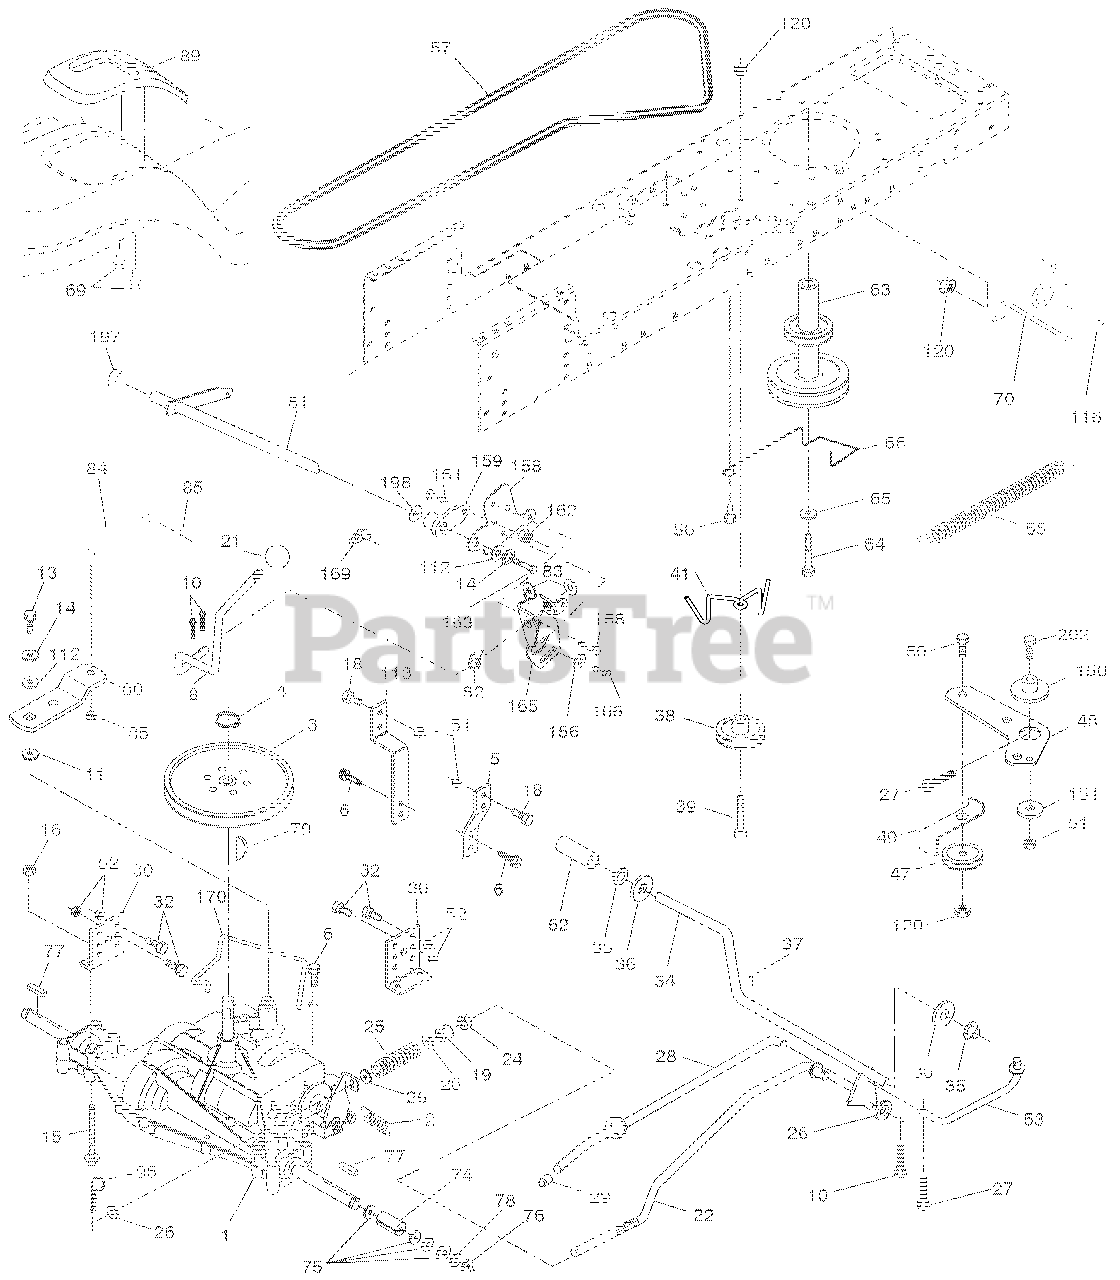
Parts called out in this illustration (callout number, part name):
2	Spring Return Brake T/a Zinc
3	PULLEY.TRANSAXLE.18/20"TIRES
4	Ring, Retainer
5	Strap Torque 30 Degrees
6	SCREW.5/16-18X3/4.SMGML.TAP/R
8	Rod Shift Fender Adjust Lt
10	Pin Cotter 1/8 x 1 Cad
11	WASHER.PLATE.SHF..388 SQ.HOLE
13	BOLT.1/4-28 UNF.GR8.W/PATCH
14	Washer, Lock 1/4
15	BOLT.HEX.FLGHD.5/16-18.GR.5
16	Locknut, Washer Insert 5/16-18
18	Bolt, Fin Hex 3/8-16 unc x 1
19	Locknut, Washer Insert 3/8-16
22	Rod Brake Blk Zinc 26 840
24	Nut, Hex, Jam 3/8-16
25	Spring Rod Brake 2 00 Zinc
26	WASHER.13/32 X 13/16 X 16 GA.
27	PIN.COTTER.1/8 X 3/4.CAD.
28	Rod Brake Parking LT/YT
29	Cap Brake Parking
30	Bracket Mtg Transaxle
32	Bolt, Hex Head 5/16-18 x 3/4
34	Shaft Asm Pedal Foot
35	BEARING.NYLON.BLK..629 ID.
36	Washer 21/32 x 1 x 16 Ga.
37	Pin Roll 3/16 x 1"
38	Pulley Composite Flat
39	BOLT.RDHD.3/8-16UNC X2-3/4 GR5
41	Keeper Belt Flat Idler
47	Pulley Idler V Groove
48	Bellcrank Asm
49	Retainer Belt Style Spring
50	BOLT.CARR.SH.3/8-16X1-1/2.GR5
51	Nut, Hex, Crownlock 3/8-16
52	Nut, Hex, Crownlock 5/16-18
53	Link Clutch
55	SPRING.RETURN.CLUTCH.6.75
56	Screw 3/8-16 x <
57	V-Belt Ground Drive
62	COVER.PEDAL.BLK.ROUND
63	Engine Pulley
64	BOLT.HEX.7/16-20X4XGR5-1.5THR.
65	WASHER.LOCK.HVY HLCL.SPR.7/16
66	Keeper Belt Engine Foolproof
69	SCREW.HEX.WSH.HI-LO.1/4X1/2UNC
70	Guide Belt Mower Drive RH
74	SPACER.AXLE.HYDRO/PEERLES
75	WASHER.25/32 X 1 1/4 X 16 GA.
76	E-RING.#5133-75
77	KEY.SQUARE.2.0 X .1845/.1865
78	WASHER.25/32 X 1-5/8 X 16GA.
79	Key Woodruff #9 3/16 x 3/4
80	Arm Shift
81	Shaft Asm Cross Tapered Pmst/2
82	Spring Torsion T/a
83	Washer 17/32 x 3/4 x 16 Ga.
84	Link Transaxle
85	NUT.LOCK.CENTER.1/4-28 FNTHD.
89	Console Shift STLT
96	Retainer Spring
112	WASHER.9/32 X 3/4 X 10 GA.
113	Strap Torque LT
116	Bolt, Carriage 3/8-16 x 1
120	Nut, Hex, Flangelock 3/8-16
150	Spacer Retainer
151	WASHER.13/32 X 2 X 10 GA.
156	Washer Srrted 5/16ID x 1.125
158	Bracket Shift Mount
159	Hub Tapered Flange Shift Lt
161	Bolt Rdhd Sqnk 1/4-20 x 3/4
162	Nut Crownlock 1/4-20 unc
163	Bolt Hex Fin 1/4-20 unc x 1 Gr
165	Bracket Pivot Lever
166	Screw 5/16-18 x 5/8
168	Bolt Shoulder 5/16-18 x .561
169	Plate Fastening
170	Keeper Belt Transaxle Gear
197	Nyliner Snap-In
198	Washer Nyliner
202	BOLT.RDHD.3/8-16UNCX1-3/4.GR5
